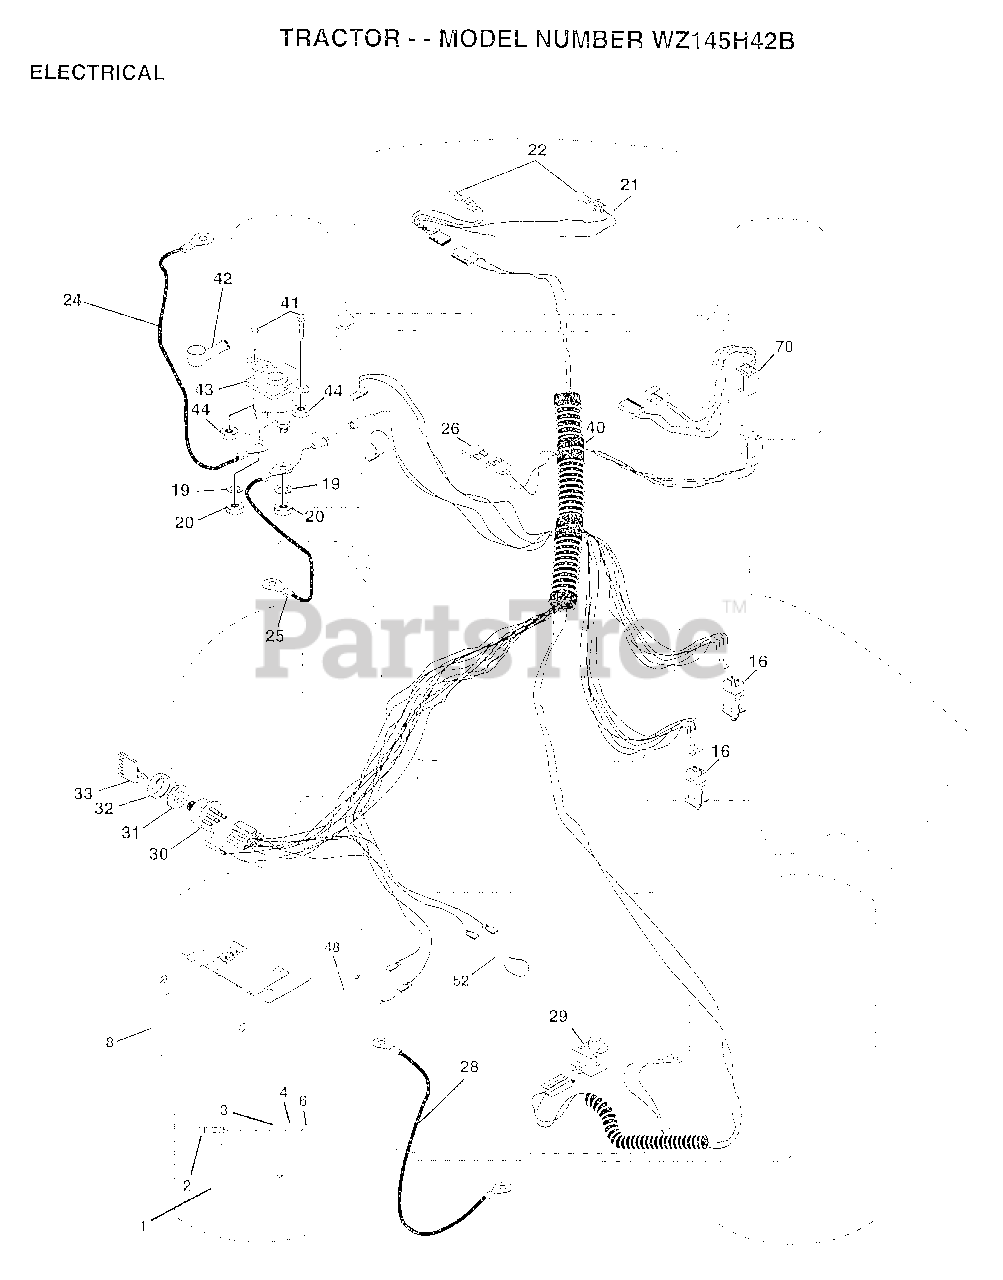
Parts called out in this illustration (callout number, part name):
3	WASHER
4	LOCKWASHER
8	"CASE,BATTERY.MECH"
16	SWITCH INTERLOCK
20	NUT
21	"HARNESS,LIGHT SOC"
22	HEADLAMP BULB
24	"CABLE T, BATTERY"
25	CABLE.BTRY.6GA.RD
26	FUSE HYT
28	CABLE T
29	SWITCH SEAT
30	SWITCH IGN 4POS
31	NUT IGNITION
32	COVER KEY SWITCH
33	KEY
40	HARNESS-IGNITION
41	BOLT HXHD FIN
44	NUT HXKEP 1/4X20
48	ADAPTER AMMETER
52	PROTECTION LOOP
70	HARNESS.ENG.DUAL
